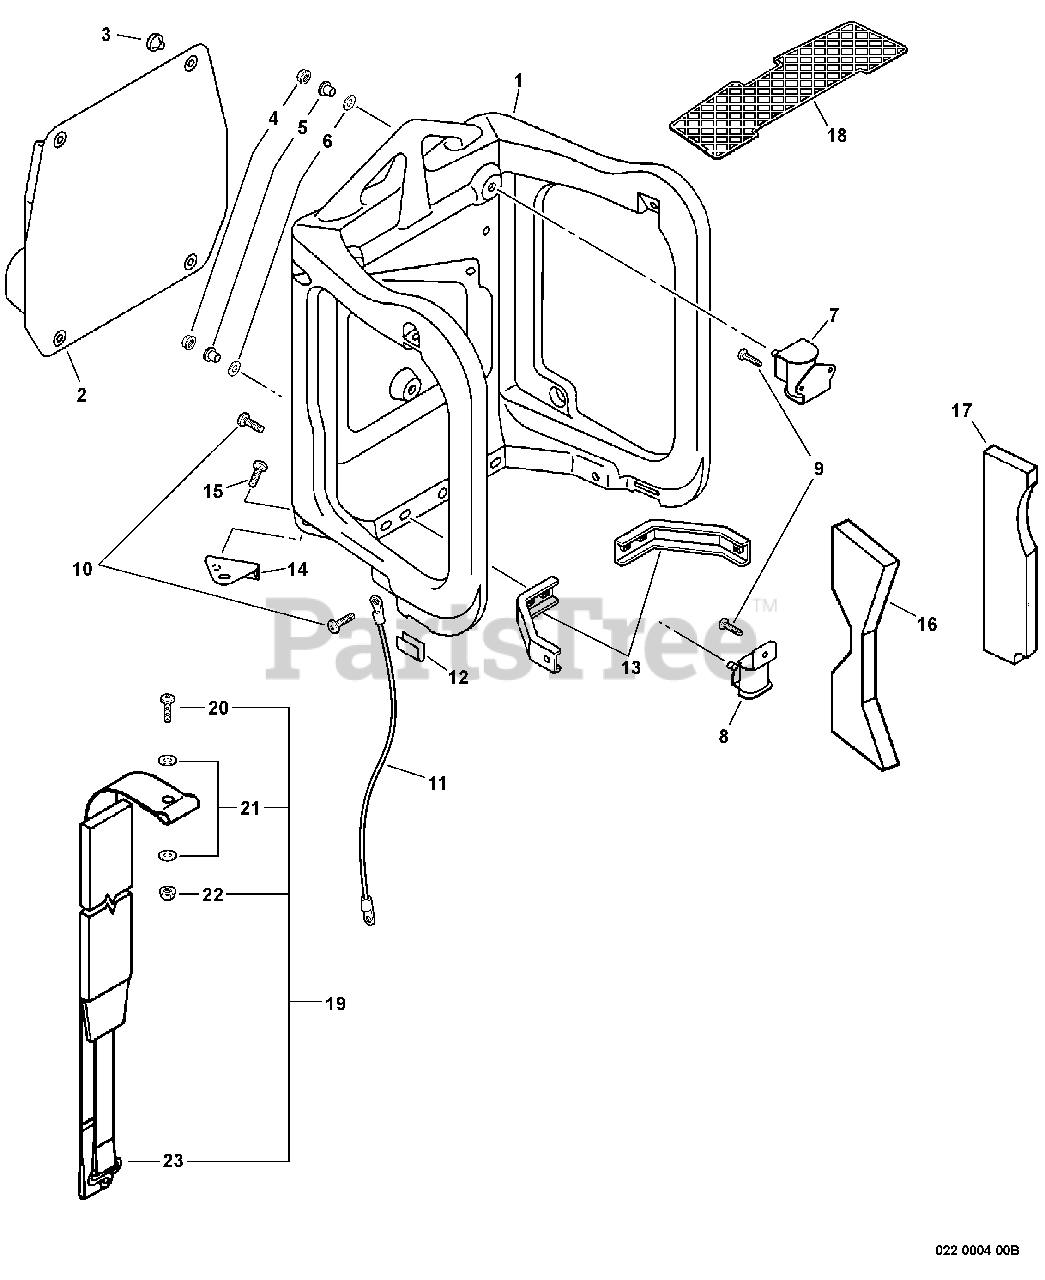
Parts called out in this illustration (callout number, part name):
1	FRAME, BACKPACK
2	CUSHION, BACKPACK
4	NUT, FLANGE M5
8	CUSHION
9	SCREW 5×16
10	SCREW 5×14
11	LEAD - GROUND
12	BUMPER
13	CONNECTOR, FRAME
14	BRACKET, HANGER
15	SCREW 5×20
16	PAD, FOAM - LEFT
17	PAD, FOAM - RIGHT
18	GUARD, DEBRIS
19	BACKPACK STRAP ASSY
20	SCREW 5×14
21	WASHER 5.5×18×1
22	NUT, FLANGE M5
23	RING, HARNESS
